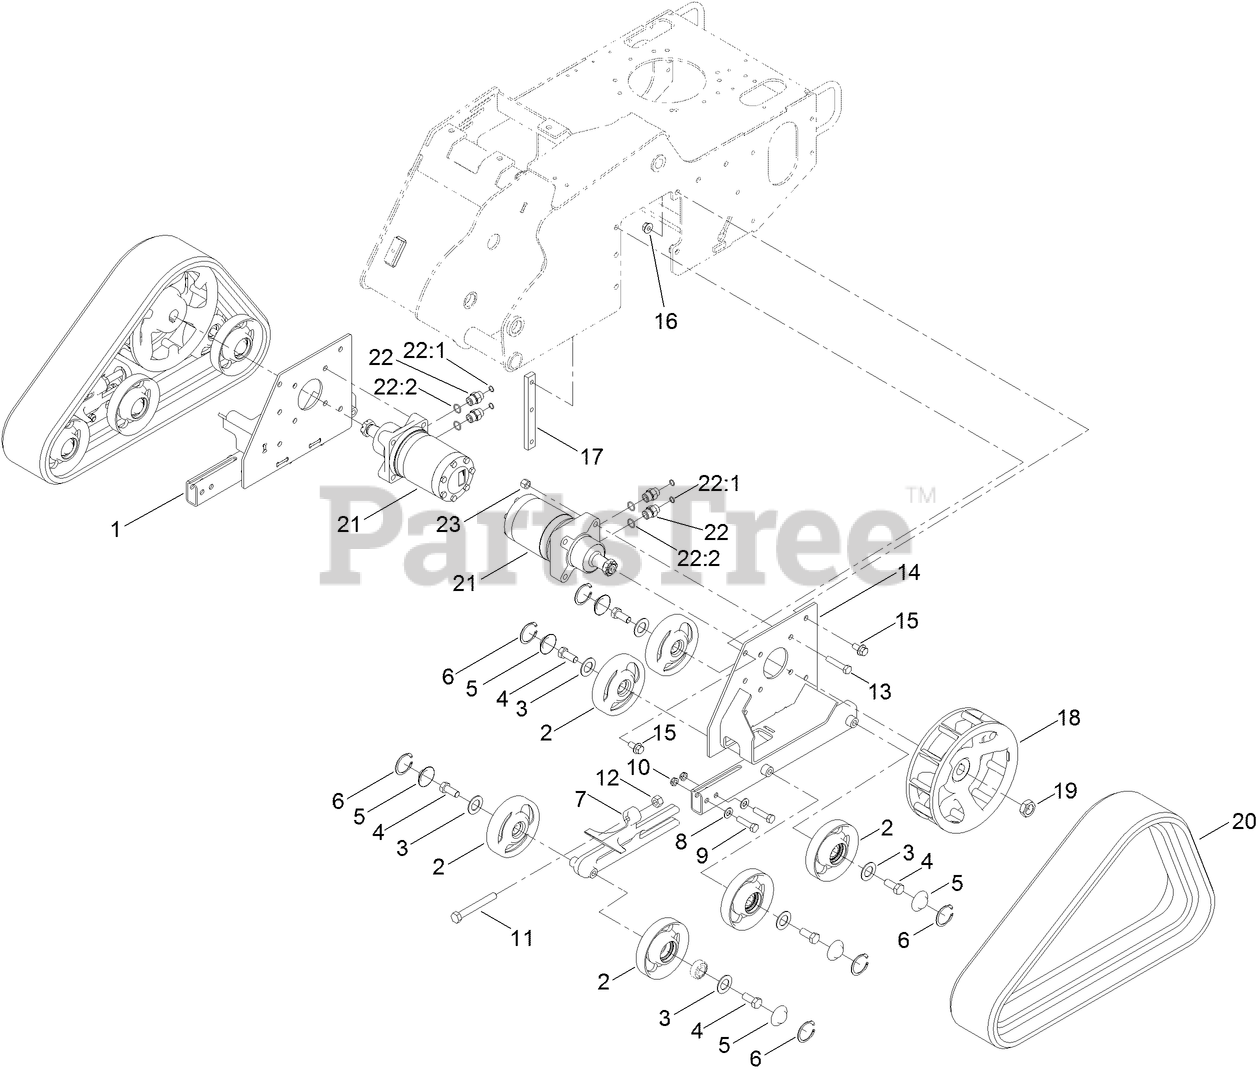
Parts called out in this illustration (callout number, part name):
1	FRAME-TRACK, RH
2	TENSIONER WHEEL ASM
3	GASKET-BOGIE
4	SCREW-HH
5	CAP-WHEEL, BEARING
6	RING-SNAP, INTERNAL
7	TENSIONER-TRACK
8	WASHER-FLAT
9	SCREW-HH
10	NUT-HEX
11	SCREW-HH, TAP
12	NUT-HEX
13	SCREW-HH
14	FRAME-TRACK, LH
15	SCREW-HHF
16	NUT-HHF
17	BAR-THREAD
18	WHEEL-DRIVE
19	NUT-LOCK
20	TRACK-RUBBER
21	MOTOR-WHEEL, HYDRAULIC
22	FITTING-STRAIGHT
22:1	O-RING
22:2	O-RING
23	NUT-LOCK, NI
